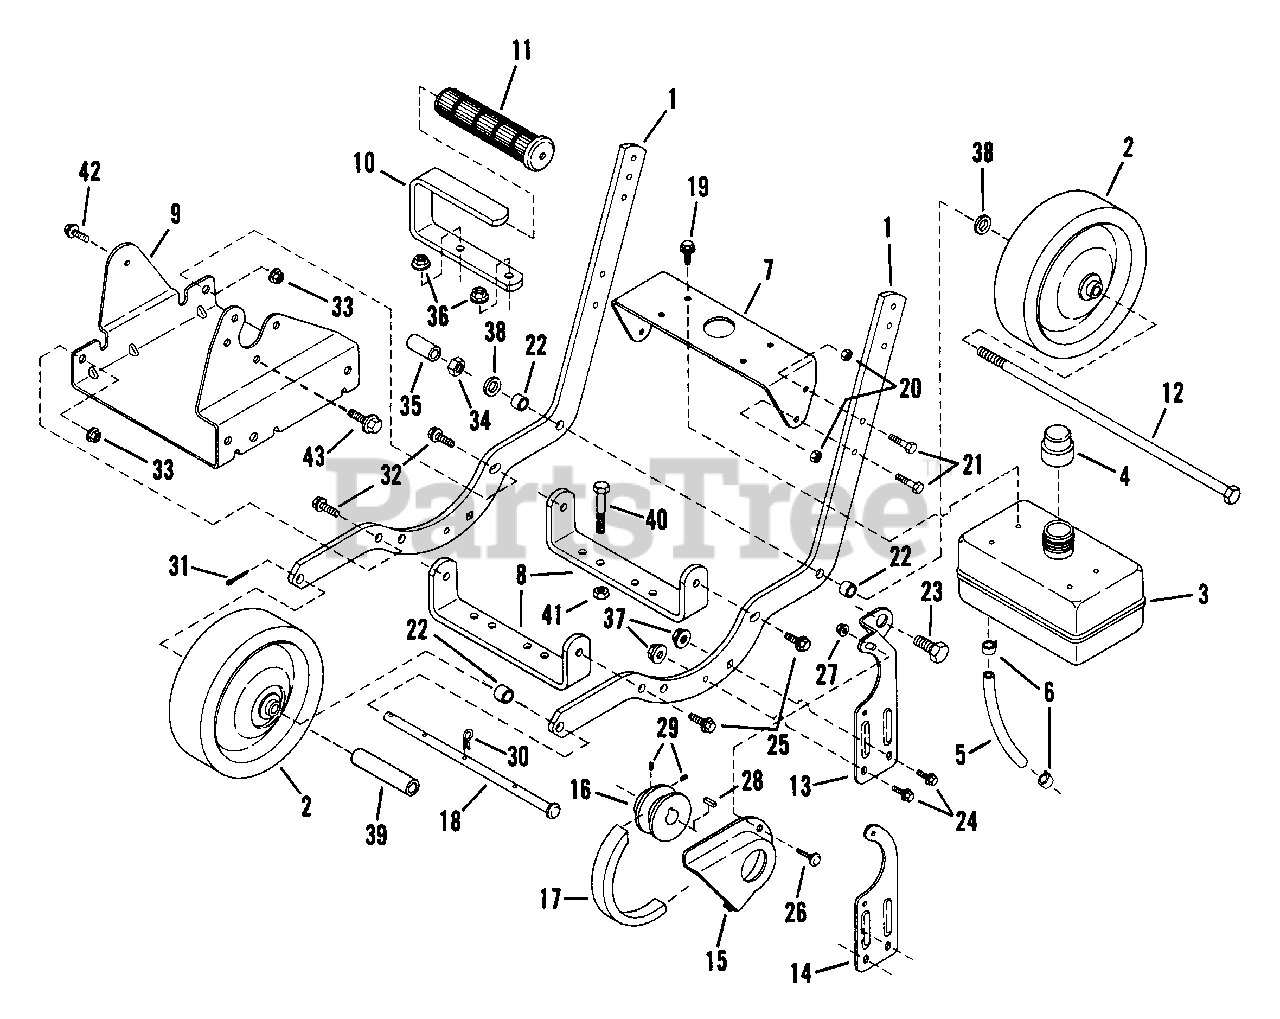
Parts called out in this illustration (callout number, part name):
2	WHEEL 8" x 1.75" (300 & 300l/C)
3	TANK, Fuel
4	CAP, Fuel Tank
5	LINE, Fuel
6	CLAMP, Fuel Line
7	BRACKET, Fuel Tank
8	SUPPORT, Engine
9	MOUNT, Engine
10	HANDLE (300 I/C Only)
11	GRIP (300 I/C Only)
12	AXLE, Rear
13	BRACKET, Guard
14	BRACKET, Guard
15	GUARD, Belt
16	PULLEY, Engine
17	BELT, Drive
18	AXLE, Front
19	SCREW, 1/4-15 x 3/4" Self-Tapping
20	NUT, 1/4-20 Hex Center Lock
21	SCREW, 1/4-20 x 7/8" Hex Cap
22	SPACER, Axle
23	SCREW, 1/2-20 x 3/4" Hex Cap
24	BOLT, 1/4-20 x 5/8" Hex Flange Lock
25	SCREW, 3/8-16 x 3/4" Self-Tapping
26	BOLT, #10-24 x 1/2" Carriage
27	NUT, #10-24 Hex Flange Lock
28	KEY, 3/16x3/16x1"
29	SCREW, 1/4-20 x 5/16 Socket Set
30	PIN, 3/32 x 1-1/2" Cotter Hair
31	PIN, 1/8 x 1" Cotter
32	BOLT, 5/16-18 x 7/8" Hex Flange Lock
33	NUT, 5/16-18 Hex Flange Lock
34	NUT, 7/16-20 Hex Center Lock
35	CAP, Axle
36	NUT, 5/16-18 Hex Flange Lock
37	NUT, 1/4-20 Hex Flange Lock (300 I/C Only)
38	WASHER, 7/16 Flat
39	BUSHING, Axle
40	SCREW, 5/16-18 x 1-1/2" Hex Cap
41	NUT, 5/16-18 Hex Center Lock
42	BOLT, 1/4-20 x 3/8 Hex Flange Lock
43	BOLT, 5/16-18 x 5/8 Hex Flange Lock
